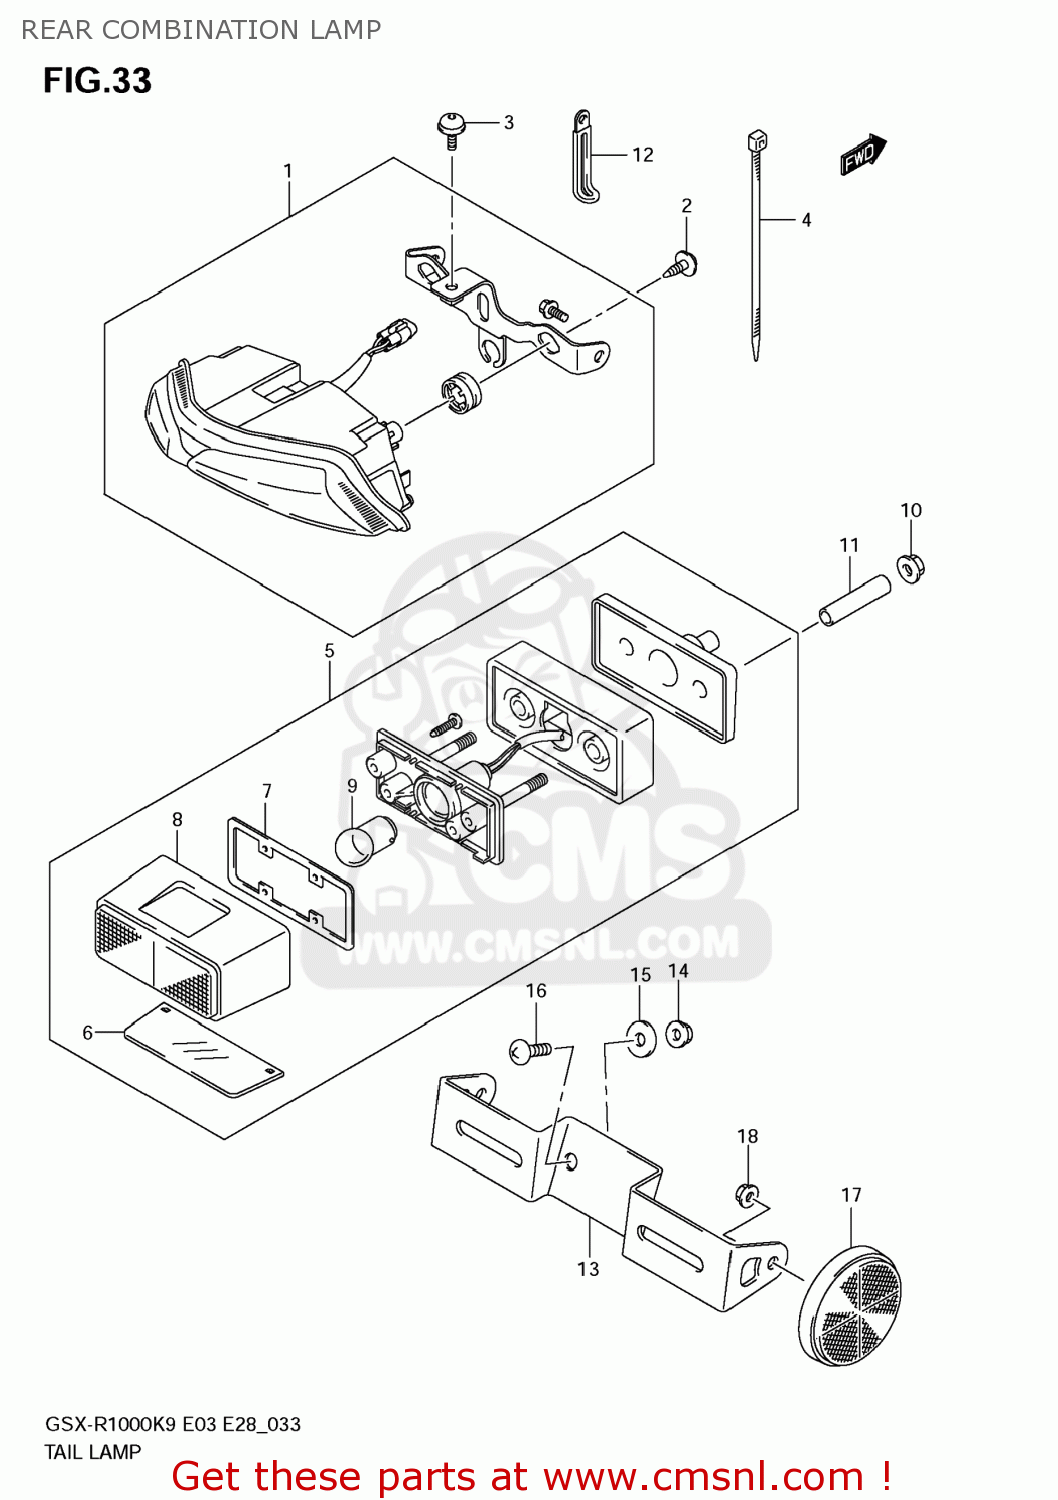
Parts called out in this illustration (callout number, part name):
1	LAMP ASSY,RR COMBINATION
2	BOLT(5X12)
3	SCREW(6X12)
4	CLAMP(L:145)
5	LAMP ASSY,LICE
6	LENS LICENCE
7	GASKET (NAS)
8	COVER,LICENSE LAMP
9	BULB(12V5W,BF150-40160A)
10	NUT
11	SPACER(6.5X9X34)
12	CLAMP(L:45)
13	BRACKET,LICENSE PLATE
14	NUT
15	WASHER(6.5X20X1.2)
16	SCREW
17	REFLECTOR ASSY,RR SIDE
18	NUT
